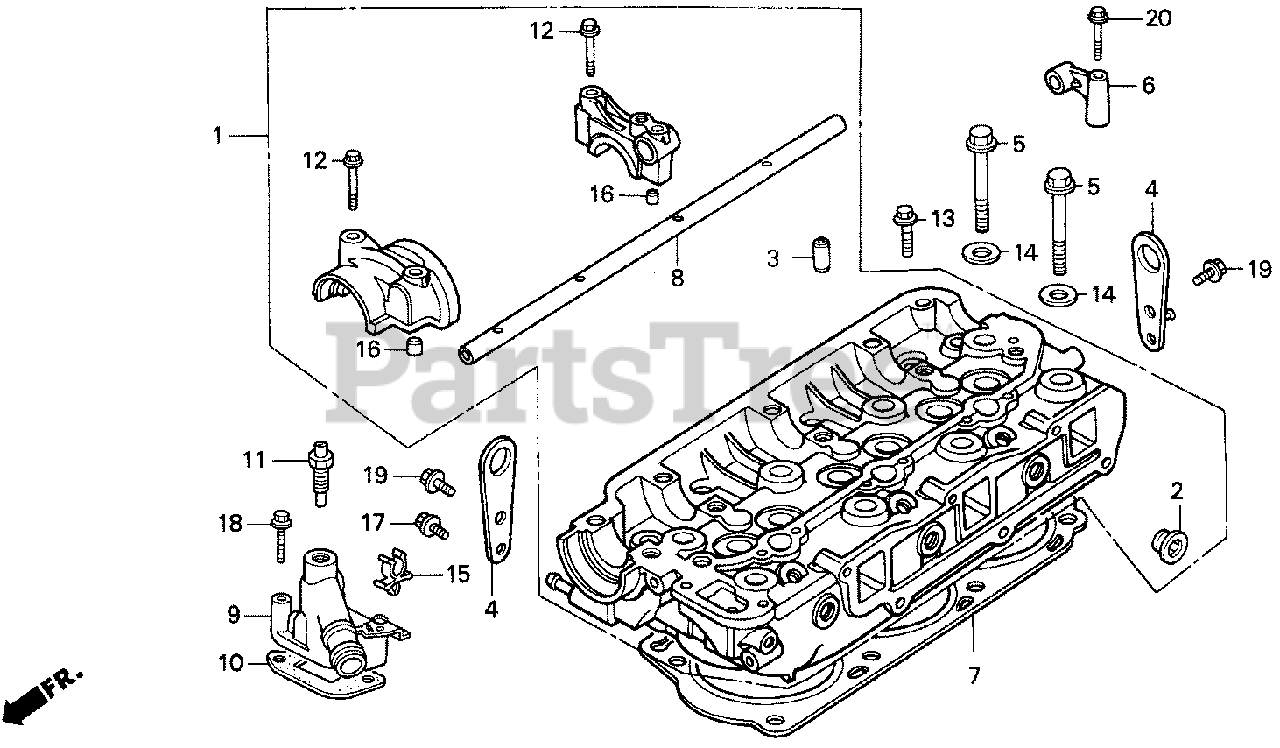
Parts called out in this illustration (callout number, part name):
1	CYLINDER HEAD ASSY.
2	BOLT, SEALING (18MM)
3	GUIDE, VALVE (OS)
4	PLATE, HANGER
5	BOLT, FLANGE (12X96)
6	HOLDER, ROCKER ARM SHAFT
7	GASKET, CYLINDER HEAD (1.25)
7	GASKET, CYLINDER HEAD (1.35)
7	GASKET, CYLINDER HEAD (1.45)
8	SHAFT, ROCKER ARM
9	JOINT, WATER OUTLET
10	GASKET, WATER OUTLET JOINT (NON-ASBESTOS)
11	BOLT, BREATHING WATER
12	BOLT, FLANGE (8X62)
13	BOLT, FLANGE (8X45) (NA USE ALT:90103-KF0-000)
14	WASHER, PLAIN (12MM)
15	CLIP, TUBE
16	PIN A, DOWEL (10X16)
17	BOLT, FLANGE (6X14)
18	BOLT, FLANGE (6X35)
19	BOLT, FLANGE (8X20)
20	BOLT, FLANGE (8X55)
